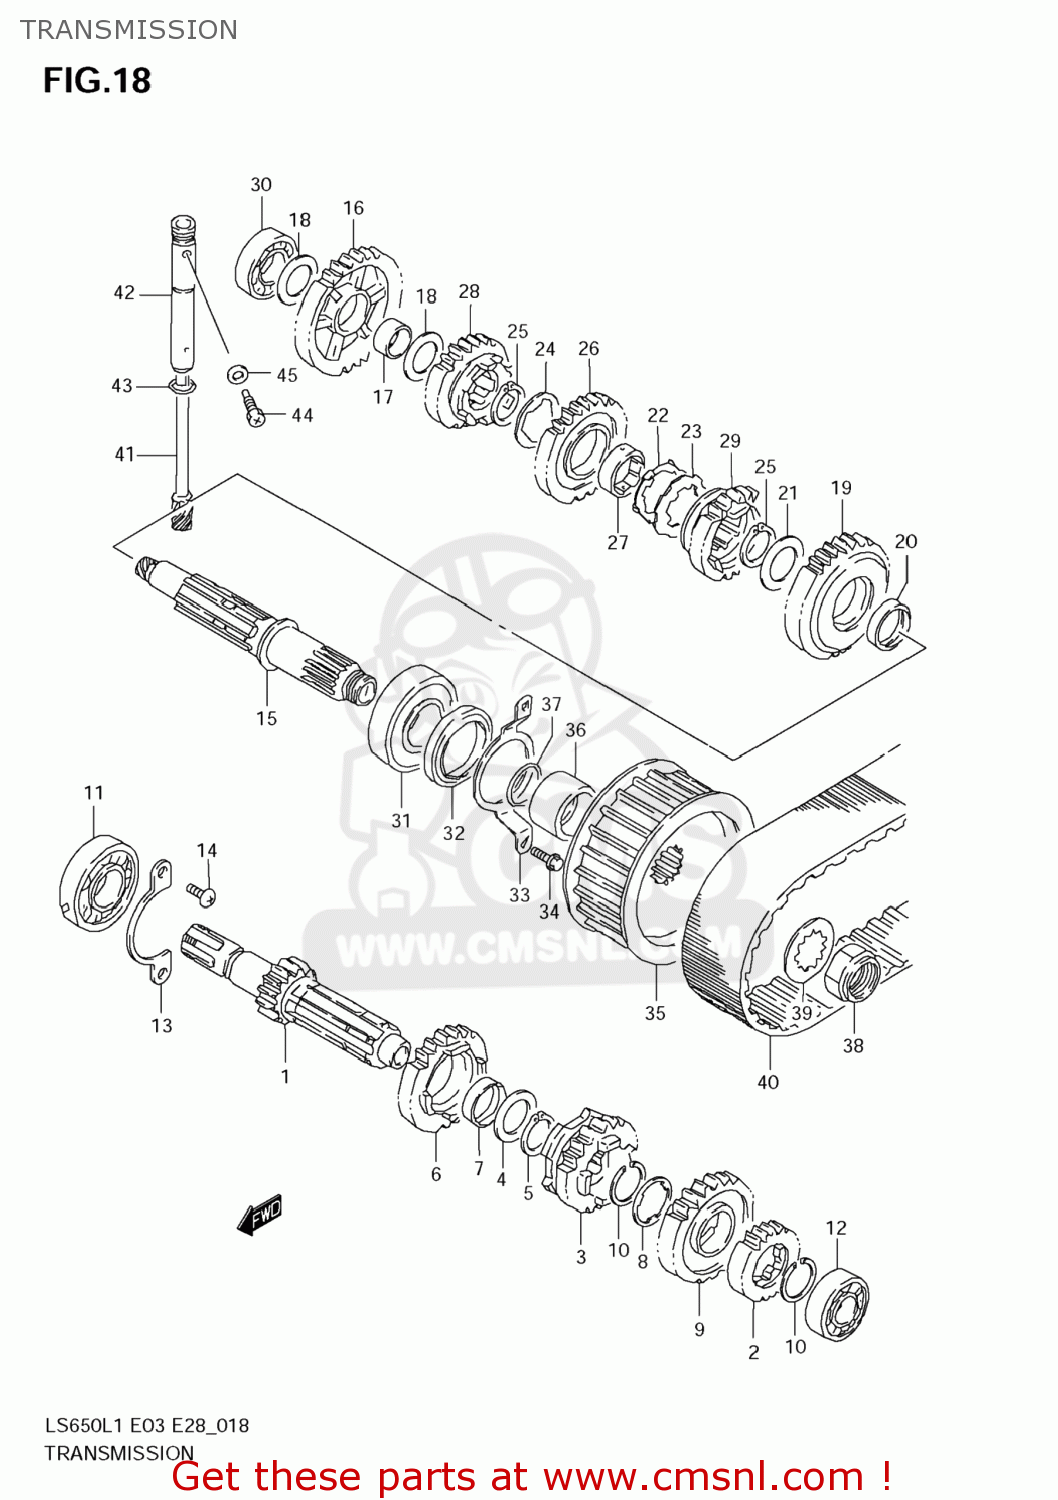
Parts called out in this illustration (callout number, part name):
1	SHAFT,COUNTER(NT:15)
2	GEAR,2ND DRIVE(NT:19)
3	GEAR,3RD DRIVE(NT:21)
4	WASHER
5	RING,SNAP
6	GEAR,4TH DRIVE(NT:23)
7	BUSH
8	WASHER,LOCK
9	GEAR,5TH DRIVE
10	CIRCLIP
11	BEARING(22X56X16)
12	BEARING(17X40X12)
13	RETAINER,CNTR SHAFT BEARING
14	SCREW
15	SHAFT,DRIVE
16	GEAR,1ST DRIVEN(NT:35)
17	BUSH(20X24X13)
18	SHIM(20X30X1)
19	GEAR,2ND DRIVEN
20	BUSH(25X29X8)
21	WASHER
22	WASHER
23	WASHER,LOCK
24	WASHER,LOCK
25	RING,SNAP
26	GEAR,3RD DRIVEN
27	BUSH,DRIVEN GEAR
28	GEAR,4TH DRIVEN(NT:22)
29	GEAR,5TH DRIVEN
30	BEARING(20X42X12)
31	BEARING(25X62X17)
32	SEAL,OIL(36X50X6)
33	RETAINER,DRIVE SHAFT OIL SEAL
34	BOLT
35	PULLEY,FR
36	SPACER,FR PULLEY
37	O RING(D:2.4,ID:23.7)
38	NUT
39	WASHER,LOCK
40	BELT,DRIVE
41	GEAR,SPEEDOMETER DRIVEN
42	SLEEVE,TACHOMETER DRIVEN GEAR
43	O RING(D:1.3,ID:9.6)
44	BOLT(6X10)
45	GASKET(6.2X11X1).2 (NAS)
